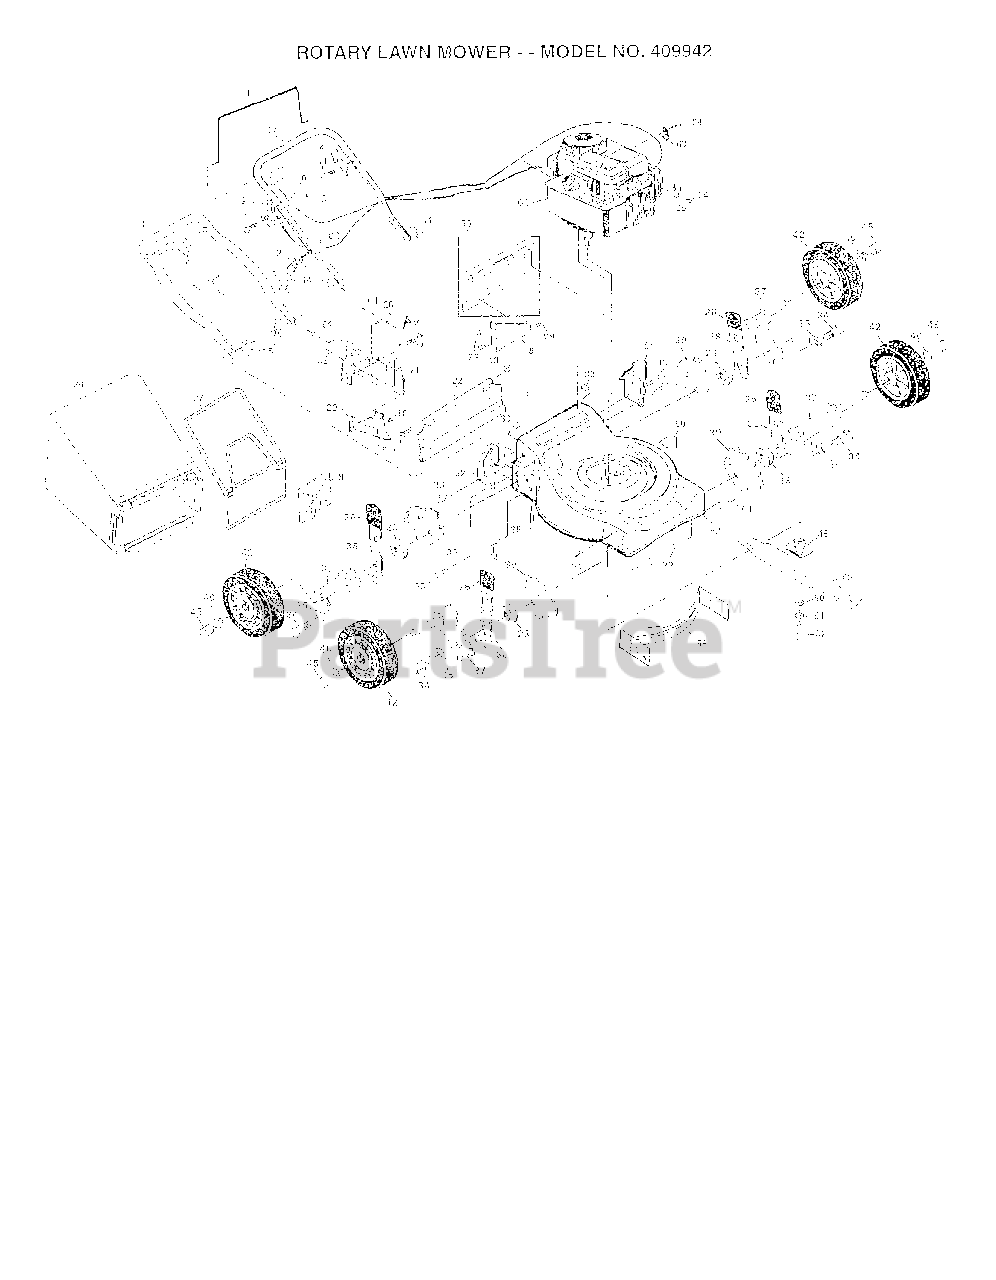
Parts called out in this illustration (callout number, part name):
1	CONTROL BAR
3	HANDLE.LOWER.STD.PNT.BLK
4	HANDL BOLT
7	MACHINE SCREW 1/4-20X2-1/4
8	Mulcher Plate
10	CABLE.MZR.51.RT.SP./PU.
11	TAPPING SCREW
12	BRACKET.UPSTOP
13	HINGE SCREW
14	NUT WING PM
15	HAIRPIN COTTER
16	SCREW.HXTAP.10-24
17	UPPER HANDLE
18	REAR BAFFLE
19	DISCHARGE BAFFLE
20	BACK PLATE
21	SIDE BAFFLE
22	REAR SKIRT
23	RP SPACER HT ADJ
24	SCREW.HEX.HEAD.WASHER.10-16
27	FRAME.CATCHER.2.5.BUSHEL
31	HANDLE BRACKET ASSEMBLY - LEFT
32	HANDLE BRACKET ASSEMBLY-RIGHT
33	SELF-TAPPING SCREW 5/16-18X3/4
35	WASHER.BELLEVILLE
37	ARM.AXLE.ASM.BZP
38	SELECTOR SPRING
39	WHEEL ADJUSTING BRACKET
40	HEX FLANGE LOCKNT
46	BOLT 3/8-16X1-1/8
48	BLADE ADAPTOR
49	20" MULCHING BLADE
50	WASHER,HARDEN
52	SCREW, HEX HD 3/8-24 X 1-3/8
56	REAR DOOR ASSEMBLY KIT
58	FRONT BAFFLE
60	DANGER DECAL
63	GUIDE CLIP PM
64	RIVET BLIND
66	NUT
